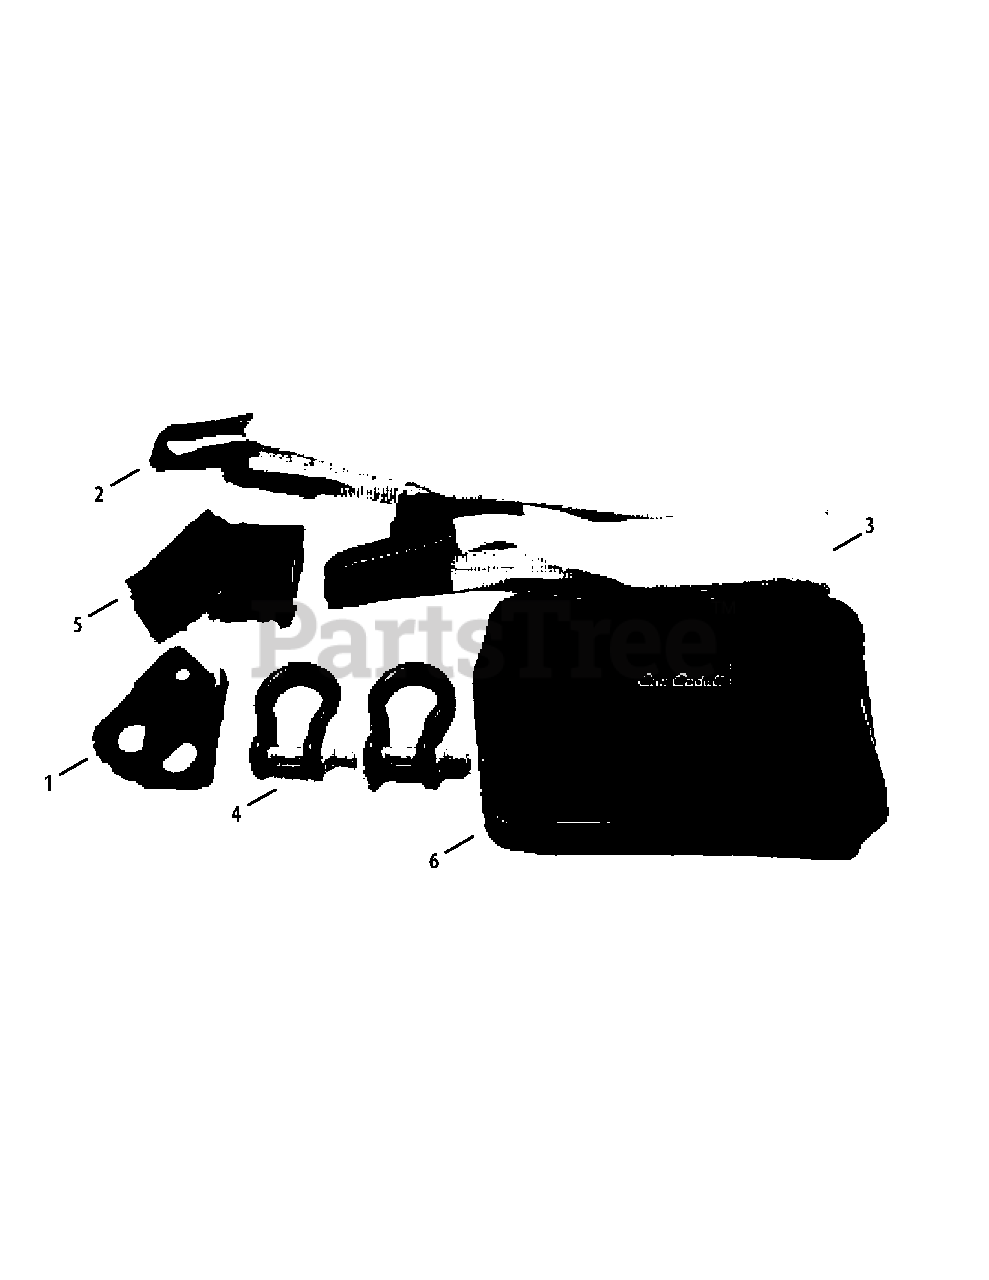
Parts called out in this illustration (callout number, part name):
1	Lock Buckle
2	Tree Saver 1.5M
3	Tree Saver, 1.0M
4	Shackle Bow
5	Wheel Chock
6	Winch Kit Bag
